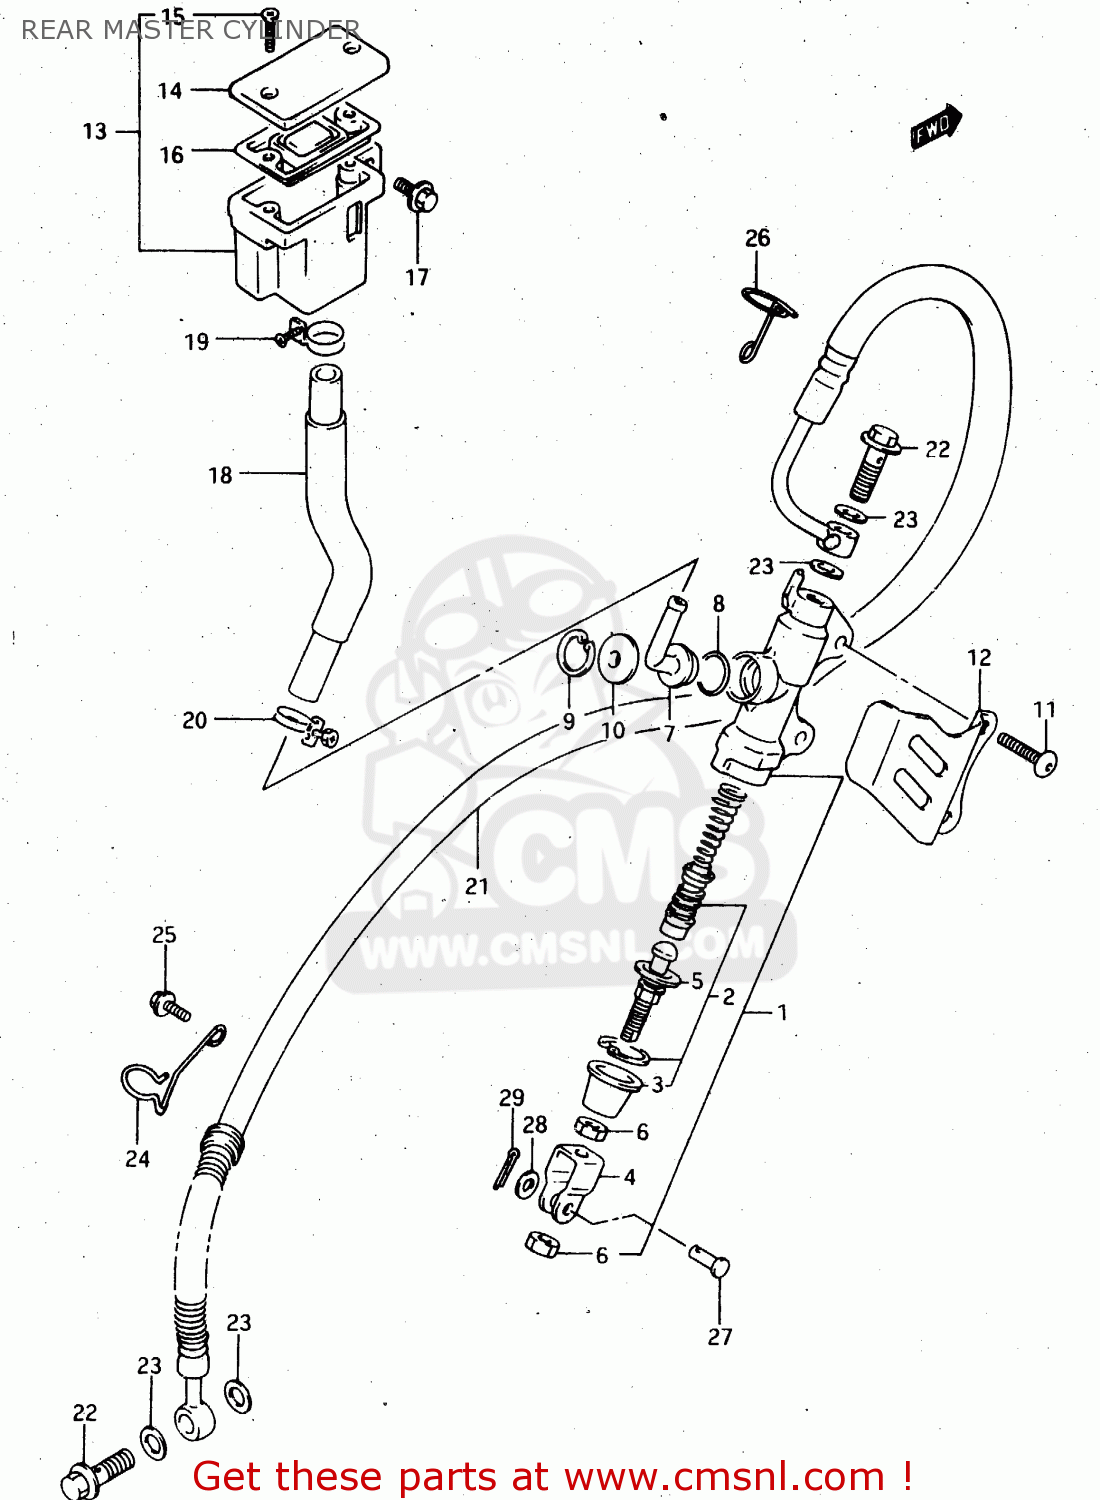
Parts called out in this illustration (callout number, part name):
1	CYLINDER ASSY,RR MASTER
2	PISTON/CUP SET
3	BOOT
4	YOKE
5	ROD,PUSH
6	NUT
7	CONNECTOR
8	O RING
9	CIRCLIP
10	COVER,DUST
11	BOLT,6X30
12	COVER,RR MASTER CYLINDER
13	TANK ASSY,RESERVOIR
14	CAP
15	SCREW
16	DIAPHRAGM
17	BOLT
18	HOSE,RESERVOIR TANK
19	CLAMP
20	CLAMP
21	HOSE,RR.BRK.
22	BOLT UNION
23	WASHER(10X15X1.5)
24	GUIDE, BRAKE HOSE NO.2
25	BOLT
26	GUIDE, BRAKE HOSE NO.1
27	PIN
28	WASHER
29	PIN
